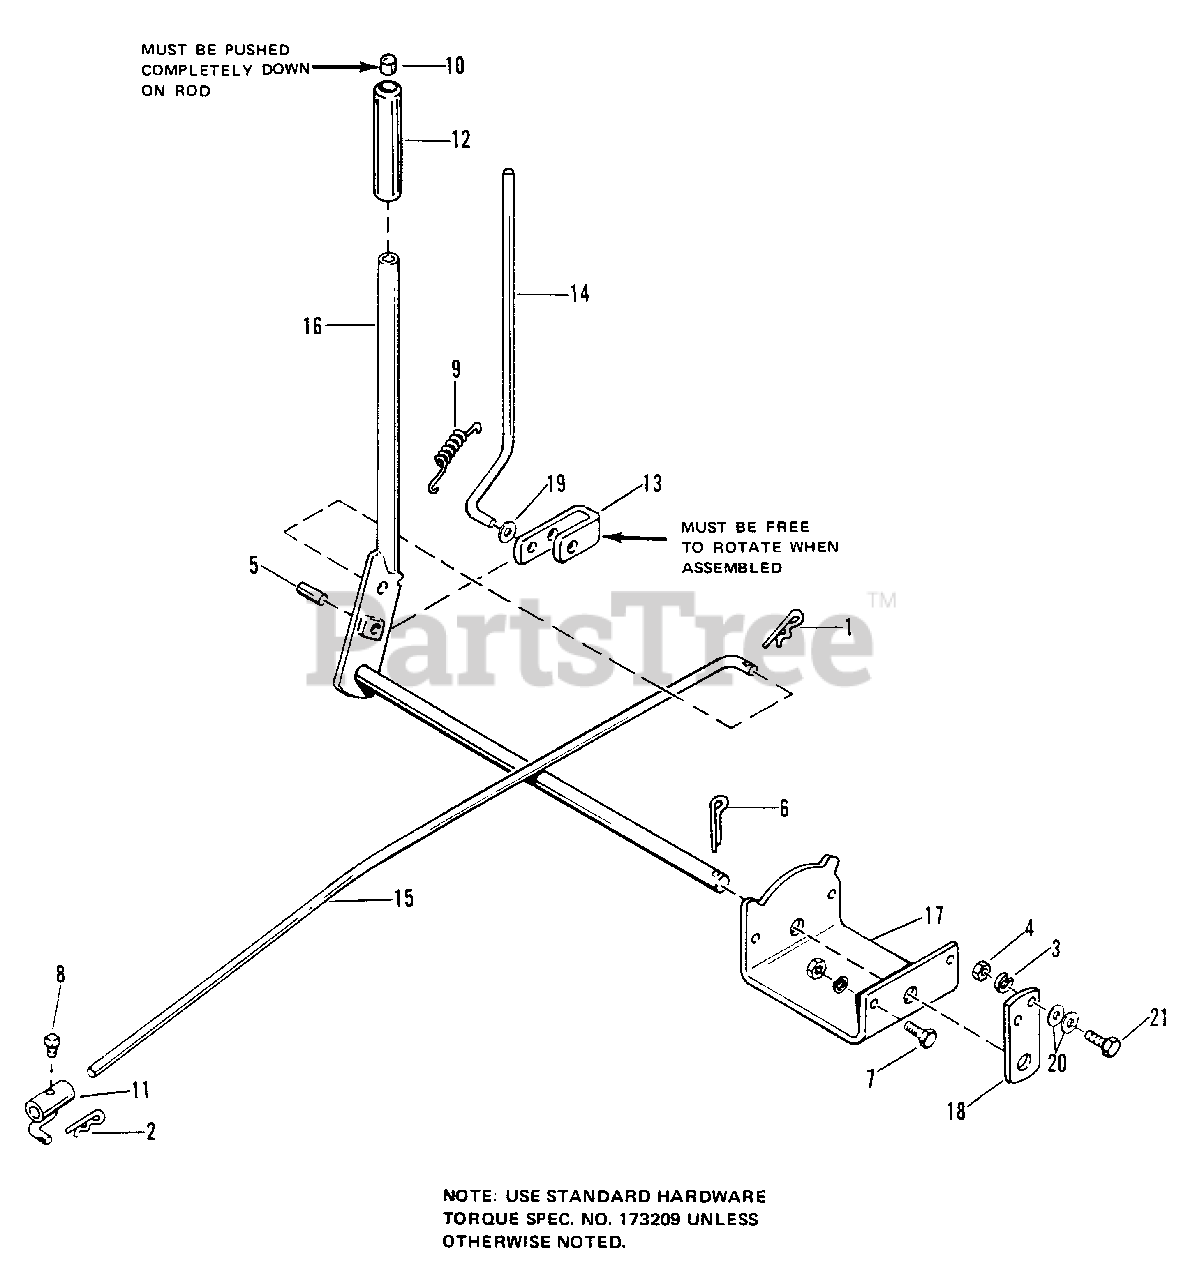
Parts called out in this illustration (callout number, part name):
1	CLIP, Spring
2	CLIP, Spring
3	LOCKWASHER, 5/16
4	NUT, Hex, 5/16-18
5	PIN, Roll, 3/8 x 1
6	PIN, Cotter, 3/32 x 1
7	CAPSCREW, 5/16-18 x 3/4
8	SETSCREW. Sq. Hd., Gr. 8, 5/16-18 x 3/8
11	GUIDE, Rod
12	GRIP, Lift Lever
13	LATCH, Lift Lever
14	LATCH, Rod
15	LIFT, Rod
16	LIFT LEVER
17	QUARDRANT, Lift
18	SHAFT, Support
19	WASHER, Special
20	WASHER, Plain, 5/16
21	CAPSCREW, 5/16-18 x 1
